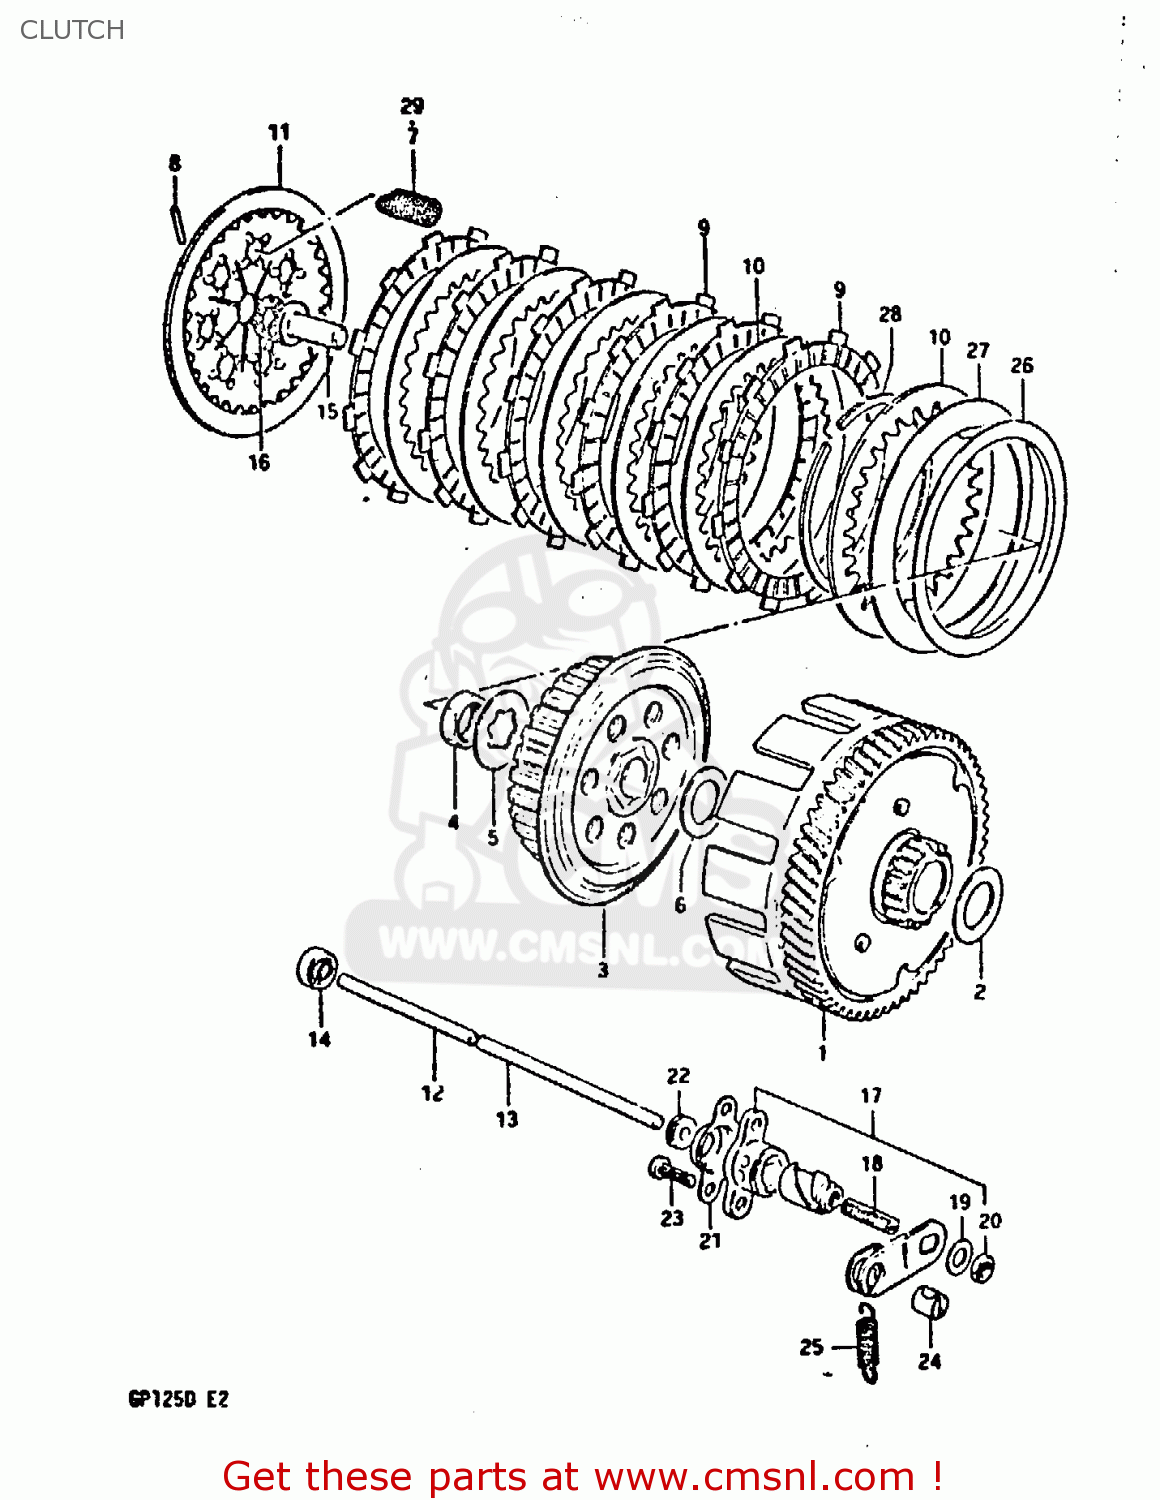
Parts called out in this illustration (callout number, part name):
1	GEAR ASSY, PRIMARY DRIVEN
2	WASHER
3	HUB,CLUTCH SLEEVE
4	NUT
5	WASHER,LOCK
6	WASHER
7	SPRING
8	PIN(2.5X19.8)
9	PLATE,CLUTCH DRIVE
10	PLATE,CLUTCH DRIVEN (NAS)
11	PLATE,CLUTCH PRESSURE
12	ROD,CLUTCH PUSH
13	ROD,CLUTCH PUSH
14	OIL SEAL
15	PIECE,CLUTCH PUSH
16	BEARING(10X22X2.8)
17	SCREW ASSY,CLUTCH RELEASE
18	SCREW
19	WASHER(6.5X16X1.2)
20	NUT 6MM
21	COVER,CLUTCH RELEASE SCREW
22	SEAL,DUST(5.3X13X5)
23	SCREW
24	PIECE,RELEASE ARM END
25	SPRING
26	SEAT,WAVE WASHER
27	WASHER
28	CIRCLIP
29	SPRING
